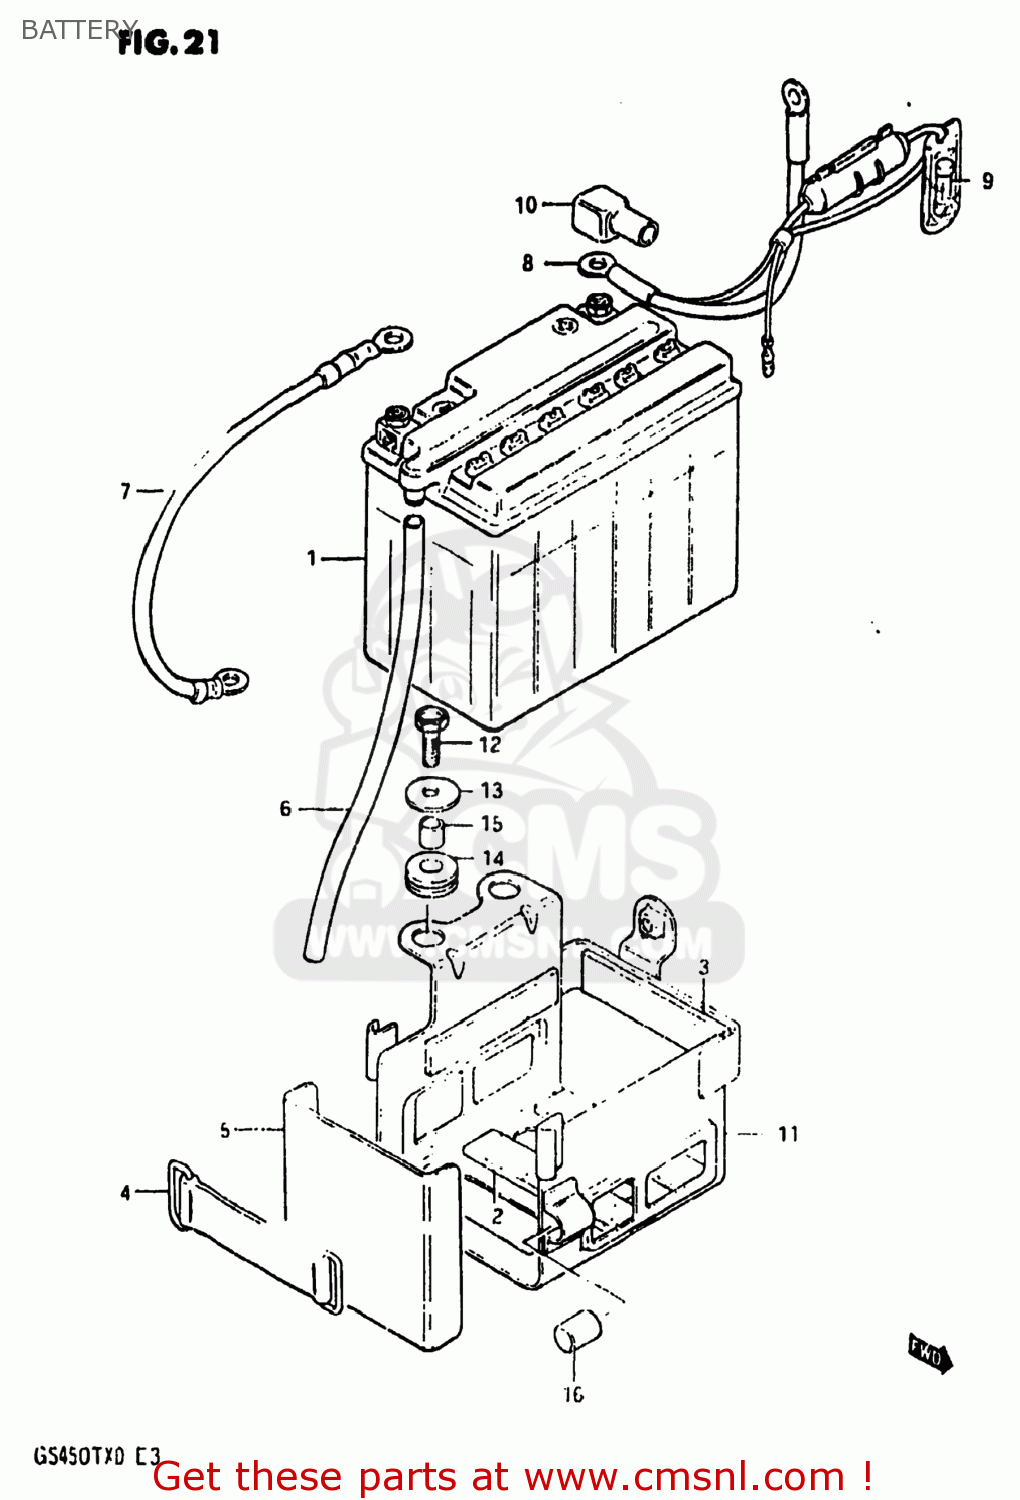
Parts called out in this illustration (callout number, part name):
1	BATTERY ASSEMBLY (12V)
2	PROTECTOR(20X90)X4
3	PROTECTOR,20X9
4	BAND
5	COVER,BATTERY
6	HOSE,BATTERY EXHAUST
7	LEAD WIRE,BATTERY(-)
8	FUSE CASE AND PLUS CABLE
9	FUSE(15A)
10	CAP,TERMINAL
11	HOLDER,BATTERY
12	BOLT
13	WASHER
14	CUSHION
15	SPACER (6.1X9X9)
16	CUSHION
